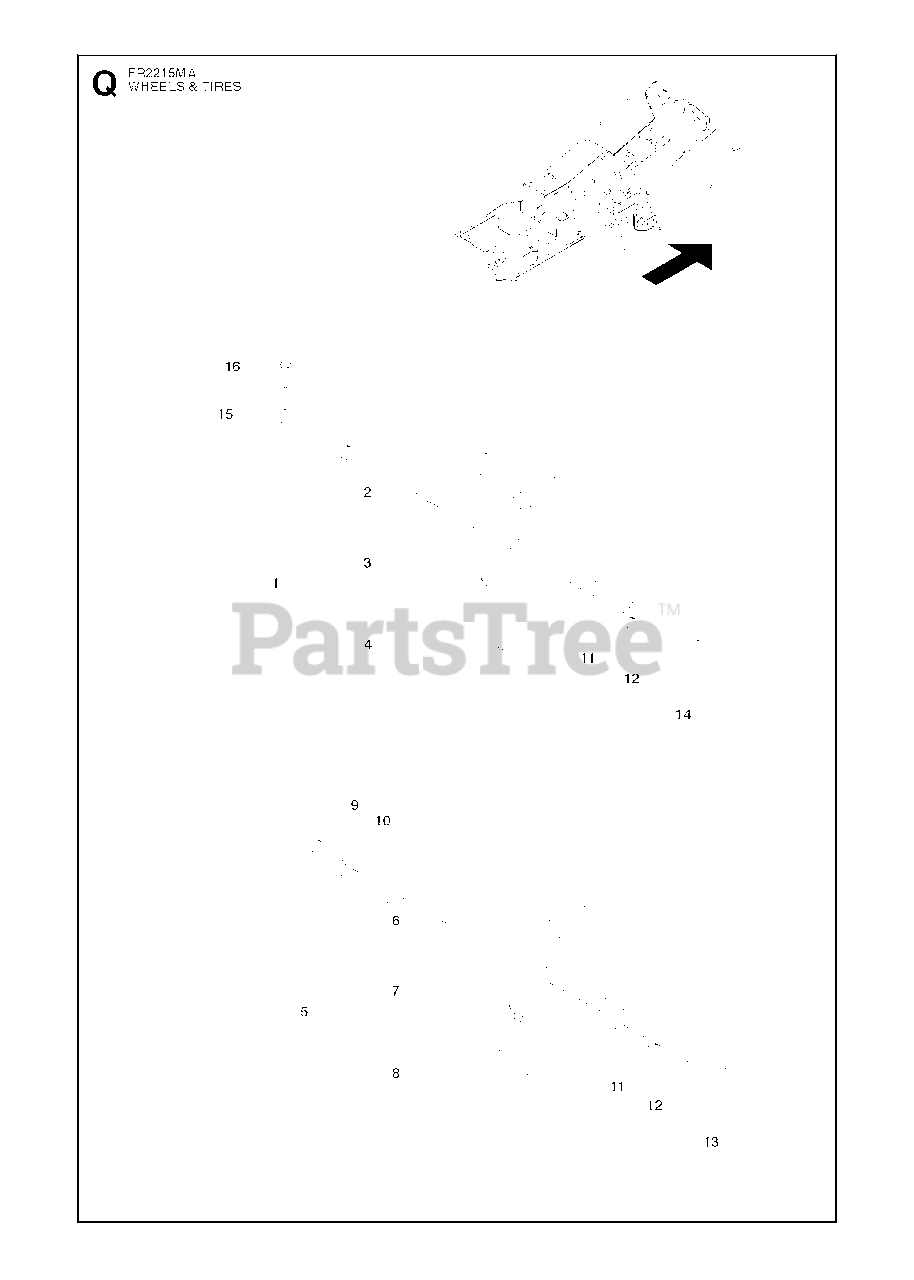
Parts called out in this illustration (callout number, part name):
10	SPACE SLEEVE
12	RETAINING RING
16	BOLT FLANGE - M8X40\
